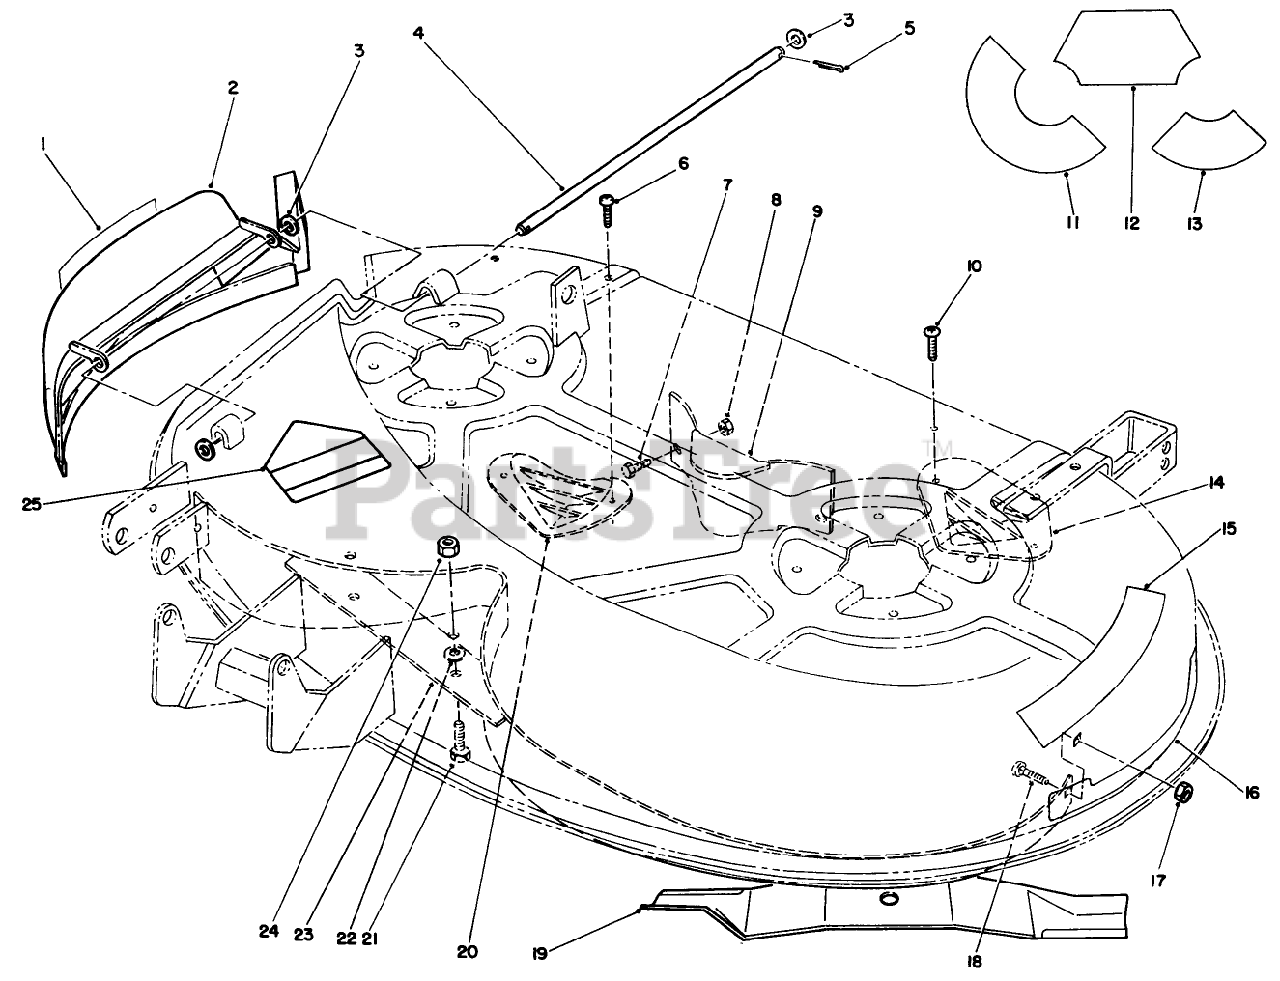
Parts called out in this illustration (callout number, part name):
1	DECAL-DANGER, THROWN OBJECT
2	Chute-Recycler
3	WASHER 5/16 SAE
5	Cotter Pin
6	SCREW-PPH, PLASTITE
7	H H C S
8	Nut
9	Baffle-Rear
10	#8 X .625" PHILPS PAN H
11	DECK-TEMPLATE LEFT
12	DECK-TEMPLATE FRONT
13	DECK-TEMPLATE RIGHT
14	PLATE-KICKER
15	DECAL-DANGER
16	DECAL-38" RECYCLER
17	Nut
18	Bolt
19	Blade
20	KICKER
21	Bolt
22	WASHER
23	Baffle-38"
24	NUT
25	DECAL-DANGER
